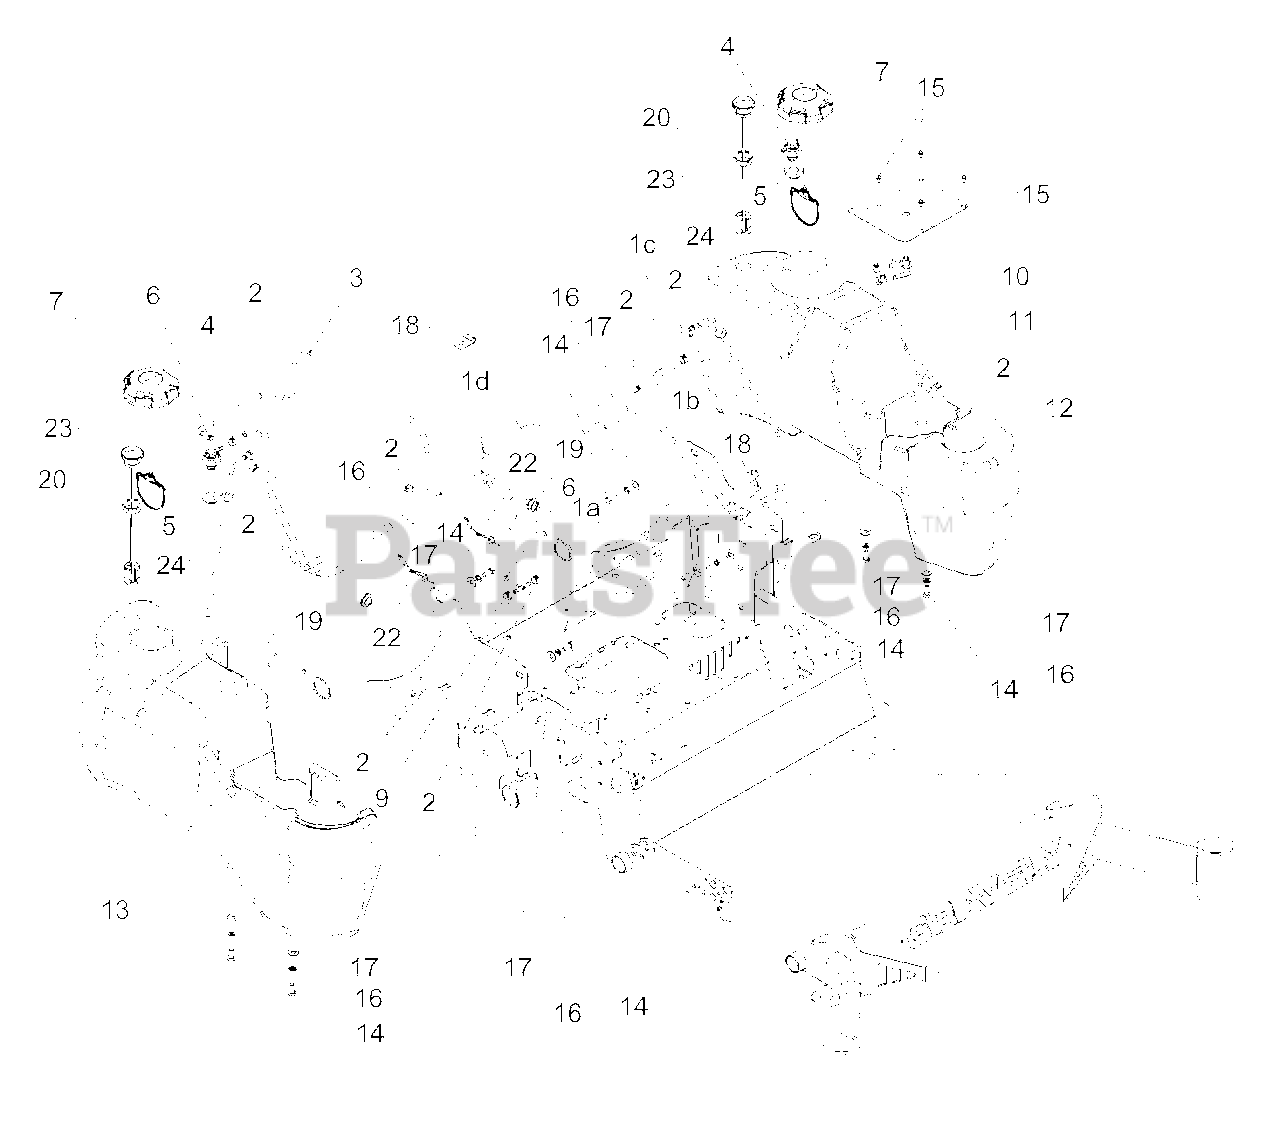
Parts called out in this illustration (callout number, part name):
2	CLAMP, FUEL LINE
3	HOSE, .188 LOW-PERM BULK GAS
4	VALVE, COMBINATION
5	GROMMET, REMOTE VENT NITRILE
6	CLAMP - HOSE, SPRING .188
7	CAP, VENT-IN FUEL
9	TEE, 1/4 HOSE RUN X 3/16 HOSE BRANCH
10	PLATE, FUEL VALVE MOUNTING
11	VALVE, FUEL
12	TANK, LH LARGE FUEL (INCLUDES 20 & 23)
13	TANK, RH LARGE FUEL (INCLUDES 20 & 23)
14	BLT-HEX .31-18X.75 GR5 YWZC
15	SCR, HWH 10-24x.38 STAINLESS
16	WSHR-LK .31X.078 REG YWZC
17	WSHR-FL-STL.38X.875X.083 YWZC
19	GROMMET, RUBBER
20	GROMMET, FUEL GAGE
22	CABLE TIE W/ TREE (.25 HOLE)
23	GUAGE, REMOTE FUEL, 12"
24	ASSEMBLY, LARGE TANK FUEL PICKUP
